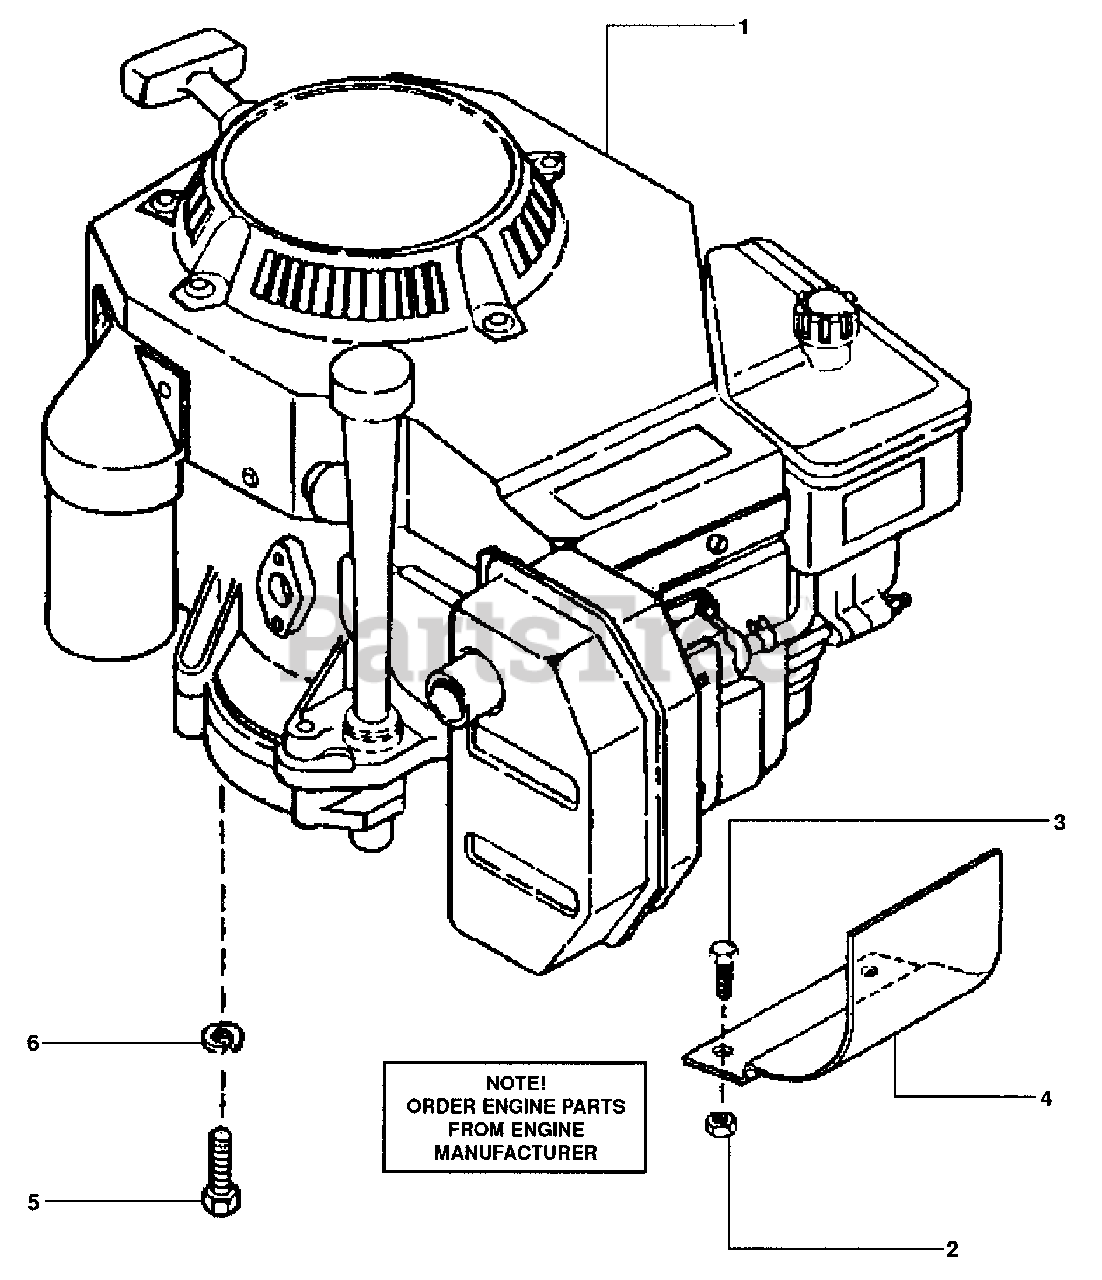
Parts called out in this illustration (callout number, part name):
2	NUT, 5/16-18 Hex Lock (Briggs & Stratton 4)
3	SCREW, 5/16-18 Hex Lock
4	SHIELD, Heat (14HP Kohler & 14HP Kawasaki)
5	SCREW, M8-1.25 X 25mm Hex Cap (Kawasaki)
5	BOLT, 5/16-18 X 1-1/2" Hex Head (Briggs & Stratton)
6	WASHER, 5/16 Split Lock
